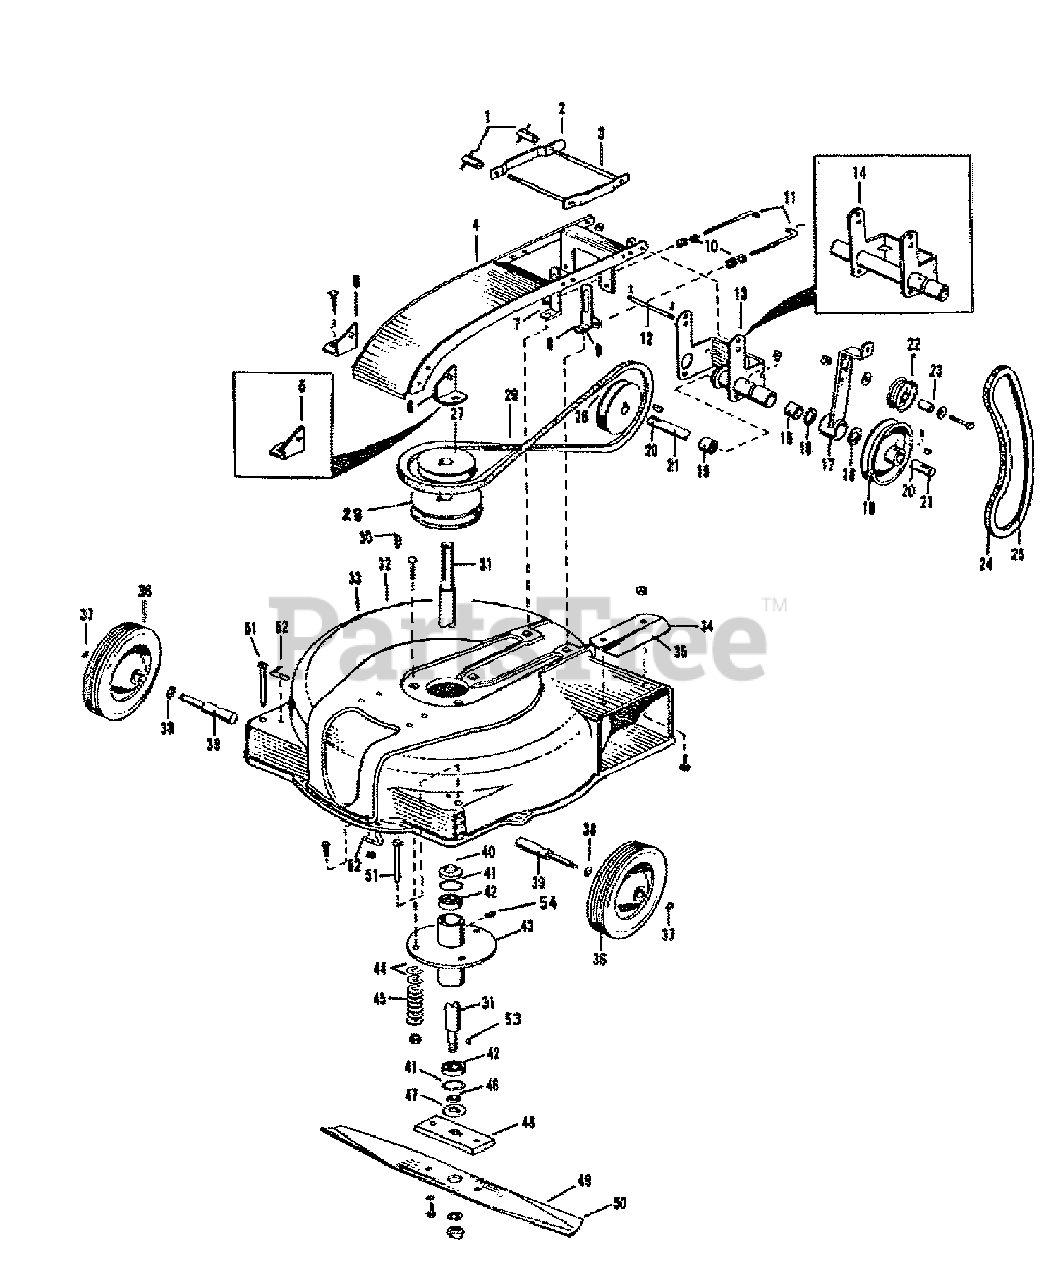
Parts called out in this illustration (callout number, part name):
1	T-NUT, Complete
2	HITCH SIDE PLATE
3	HITCH CLAMP ASSEMBLY
4	PUSH ARM ASSEMBLY
5	BRACKET, R.H.
6	BRACKET, L.H. (24")
7	SUPPORT ASSEMBLY, R.H.
8	SUPPORT ASSEMBLY, L.H.
9	SUPPORT (20")
10	SPRING (20")
12	PIVOT PIN
13	DRIVE BRACKET ASSEMBLY (24")
14	DRIVE BRACKET ASSEMBLY (20")
15	BEARING, Needle)
16	RETAINING RING
17	IDLER LEVER ASSEMBLY
20	SHAFT, Idler (24")
21	SHAFT, Idler (20")
22	IDLER PULLEY ASSEMBLY
23	INNER BEARING RACE
24	V" BELT 33" (Drive)(24" Mower)`
25	V" BELT 31" (Drive)(20" Mower)`
29	A35S SUPER COMBINE CROSS DRIVE BELT
30	KEY
32	HOUSING (24")
33	HOUSING (20")
34	DEFLECTOR (24")
35	DEFLECTOR (20")
36	WHEEL w/TIRE
37	RING, Retaining
38	WASHER, Spring Tension
41	RETAINING RING
42	BALL BEARING
43	ARBOR HOUSING ASSEMBLY
44	SHIM, .032 Thick
45	SHIM, .0625 Thick
47	WASHER, Arbor
48	ARBOR FLANGE
49	KNIFE BLADE (24")
50	KNIFE BLADE (20")
51	PIN, Lock
54	PIPE PLUG, 1/8" Standard
